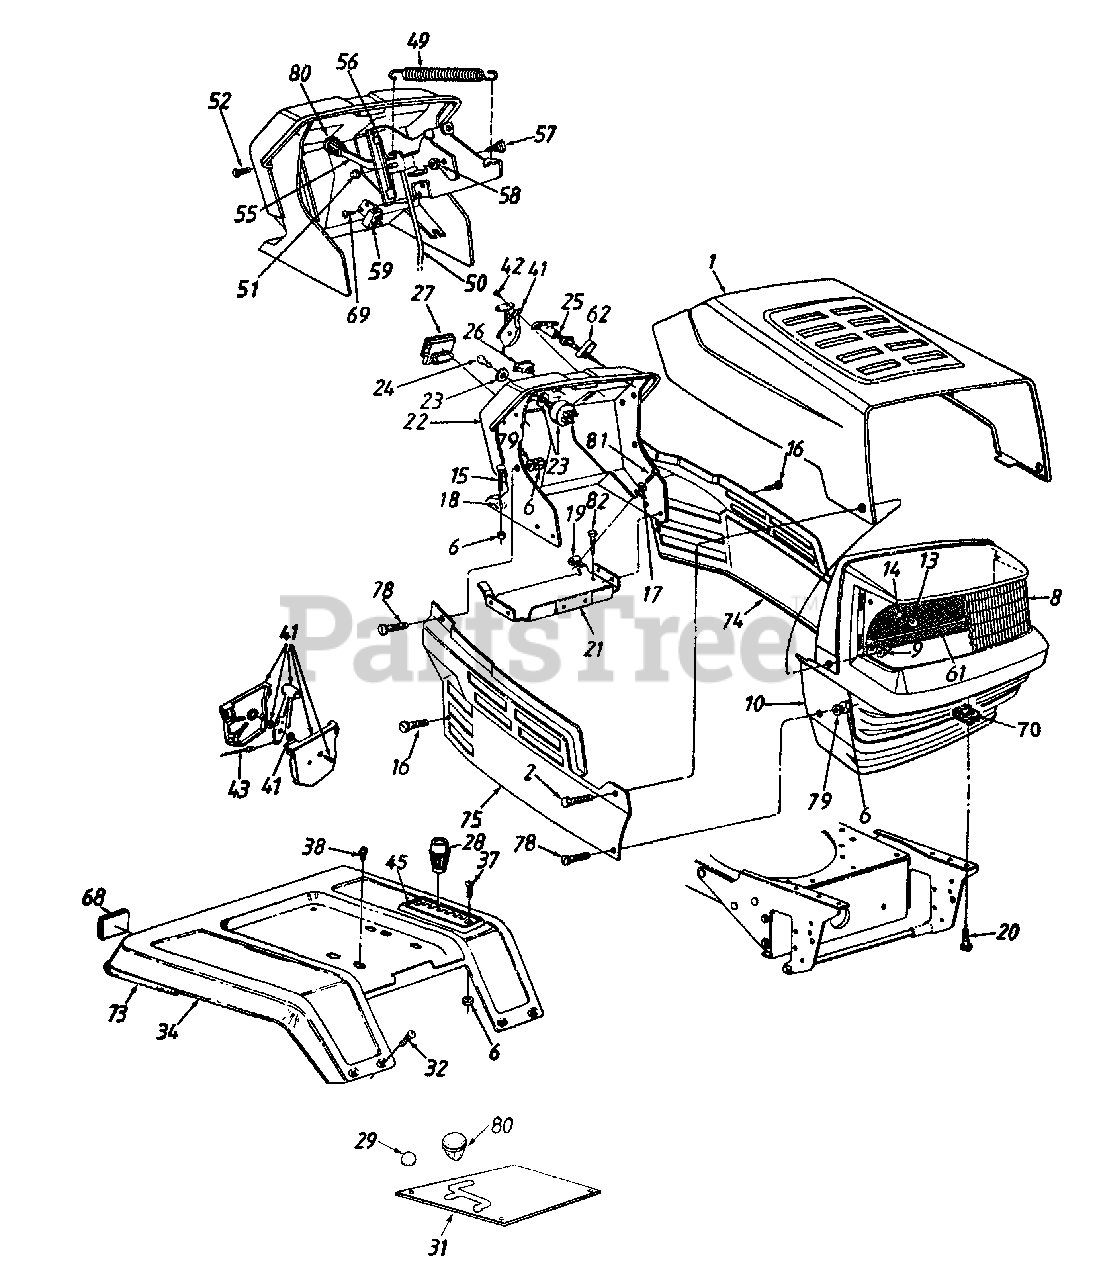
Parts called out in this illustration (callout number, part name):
6	Hex Sems Nut 1/4-20 Thd.
8	Headlight Lens w/Logo
9	Flange L-Nut 1/4-20 Thd.
10	Grille
13	Lamp
14	Socket
15	Carriage Bolt 1/4-20 x 1.0" Lg.
16	Hx Wash Hd. TT-Tap Scr. 1/4-20 x .5" L
17	Fl-Wash. .281" I.D. x .73" O.D.
18	Bolt Retainer 1/4" I.D.
19	Speed Nut 1/4-20 Thd.
20	Hex Bolt 5/16-18 x .75" Lg.
23	Ignition Switch
24	Ignition Key
25	Choke Control
27	Ammeter
28	Shift Knob
38	Hx Wash Hd. AB-Tap Scr. 5/16 x .75" L
41	Throttle Box Ass'y.
42	Truss Mach. AB-Tap Scr. #10 x .5" Lg.
43	Throttle Control Wire 35" Lg.
45	6-Speed Selector Plate
49	Ext. Spring 5.06" Lg.
50	Deck Control Rod
51	Speed Nut 1/4" Rod
52	Torx Mach. Scr. 1/4 x .62" Lg.
55	PTO Lever
58	Hex L-Nut 5/16-18 Thd.
59	Safety Switch
61	Grille Reflector Label
62	Retainer Clip
68	Reflector
69	Hx Wash. Hd. B-Tap Scr. #10 x .38" Lg.
70	U-Nut 5/16-18 Thd.
73	Trim Strip 81" Lg.
79	Bell-Wash. 1/4" I.D.
80	Small Shift Knob
81	Hex TT-Tap Scr. 1/4-20 x .75" Lg.
82	Hex AB-Tap Scr. 1/4 x .62" Lg.
